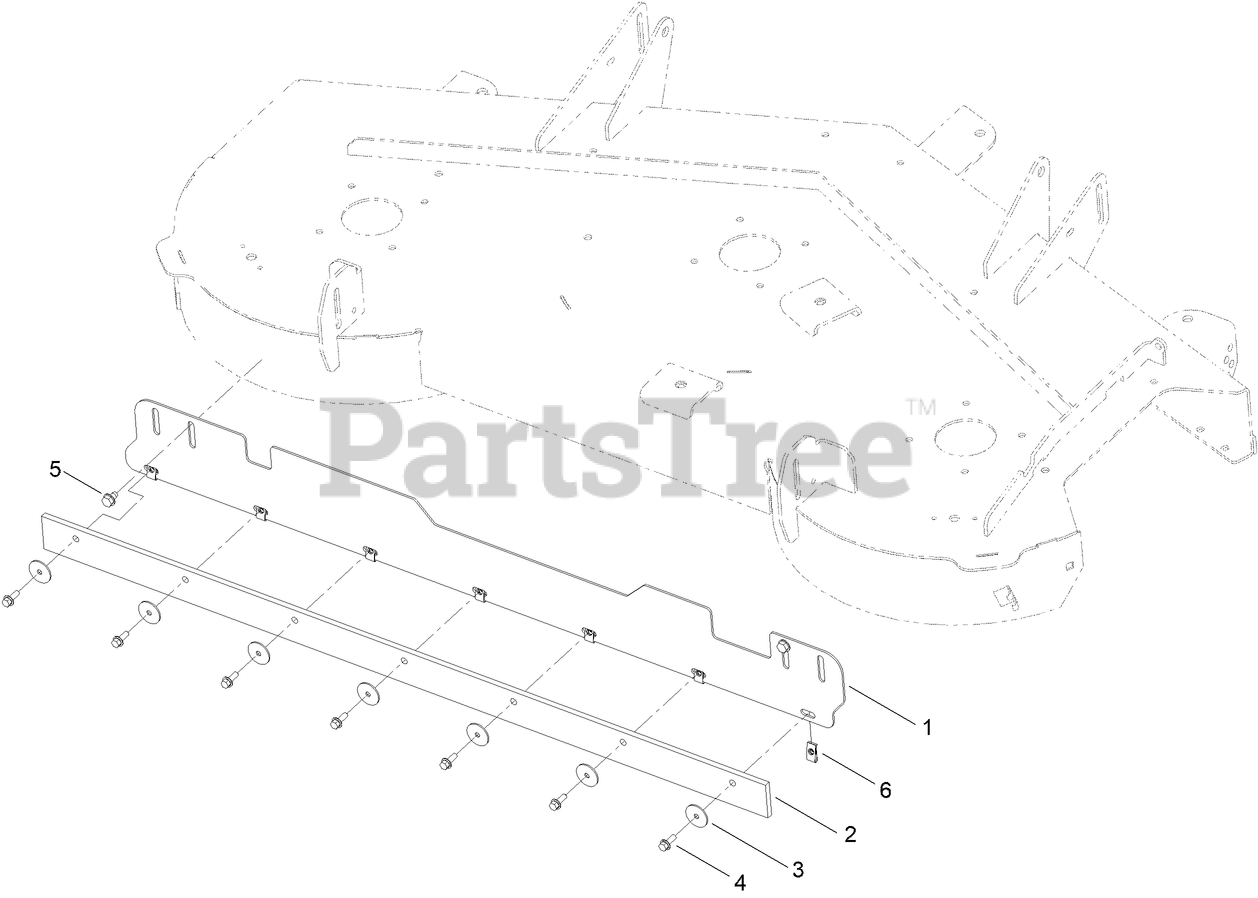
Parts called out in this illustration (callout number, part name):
1	BRACKET-STRIPING, 54/60"
3	WASHER-FLAT
4	SCREW-HHF
5	SCREW-HWH, THD ROLL
6	NUT-SPEED
